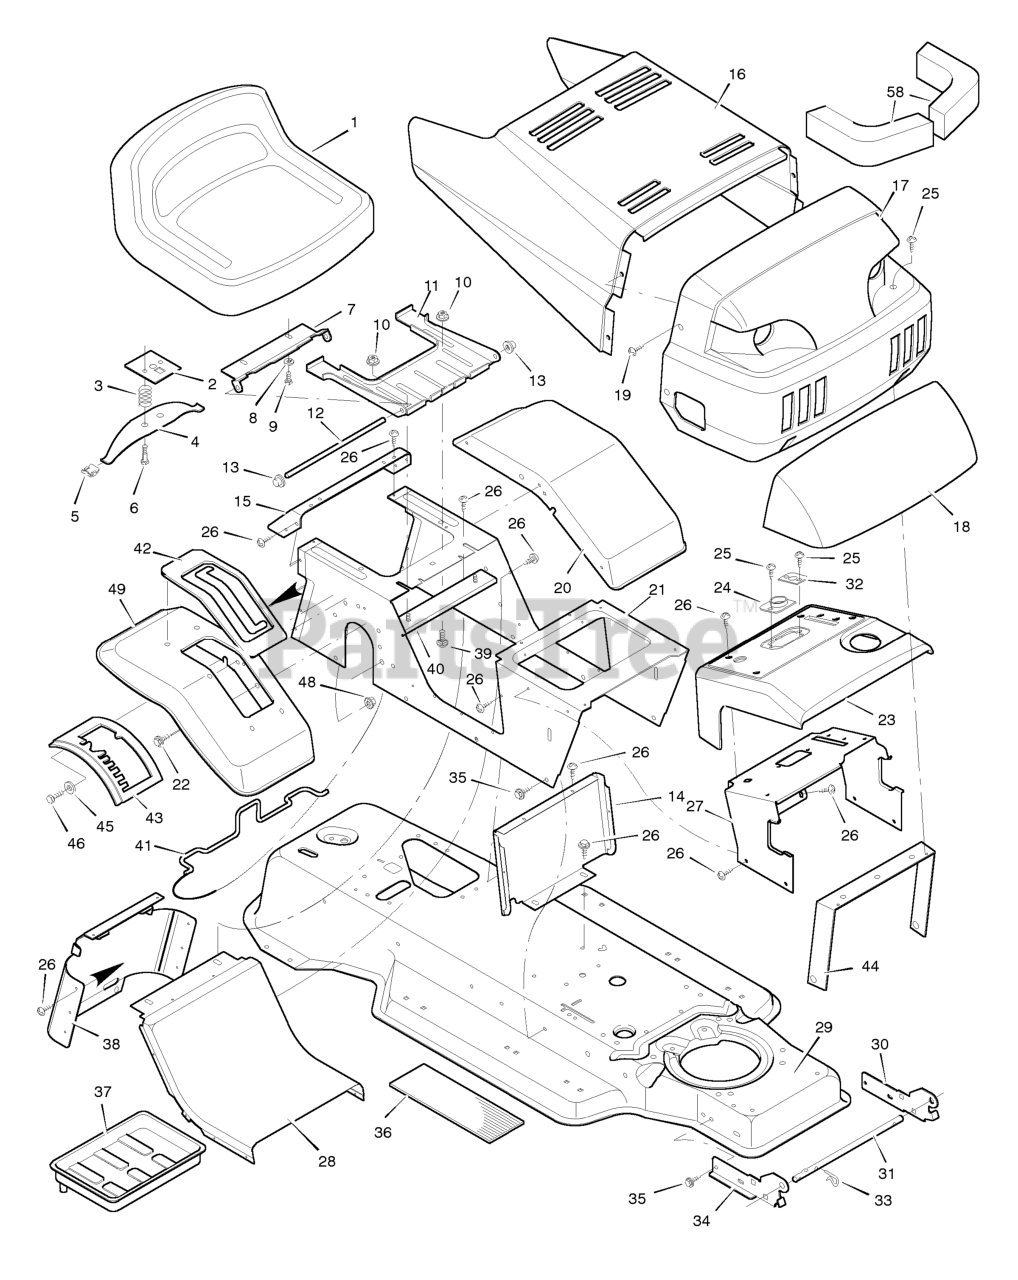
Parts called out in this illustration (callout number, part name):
2	Plate Assembly, Switch
3	Spring, Compression
4	Spring, Seat
5	Glide, Spring
6	Bolt, Shoulder
7	Support, Seat
8	Lockwasher
9	Bolt, Hex
10	Locknut, Flange
11	Bracket, Pivot
12	Rod, Pivot
13	Cap, Push On
14	Insert, Front
15	Fender, Apron
17	Grille Assembly
21	Console Assembly
23	Dash Panel
24	Bearing, Steering
26	Screw
27	Support, Dash
28	Insert, Rear
29	Frame Assembly
30	Bracket, Left Grille
31	Rod, Pivot
32	Bearing
33	Pin, Hair
34	Bracket, Right Grille
37	Tray, Battery
38	Cap, Console
39	Bolt
40	Channel Assembly
41	Clamp, Battery
42	Cover, Shift
43	Gate, Shift
44	Brace, Grille
46	Bolt, Hex
48	Locknut
49	Fender, SOG
58	Baffle, Foam Heat
